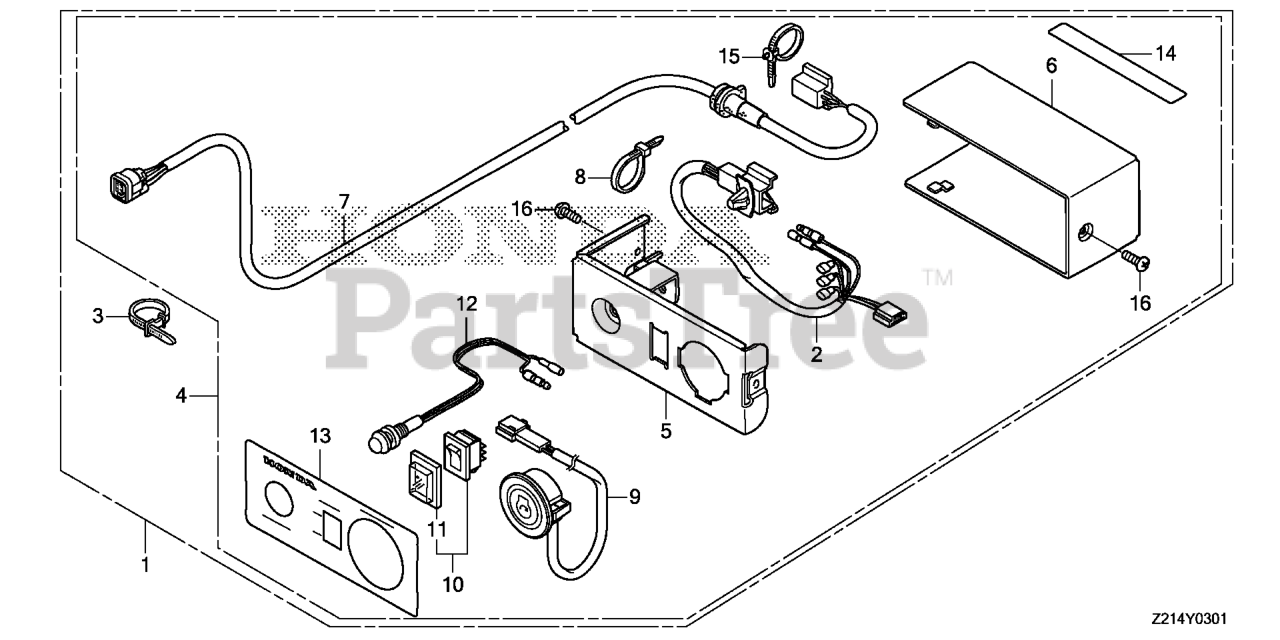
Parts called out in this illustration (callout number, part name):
1	CONTROL KIT, REMOTE (10M) *NH105* (MAT BLACK)
1	CONTROL KIT, REMOTE (20M) *NH105* (MAT BLACK)
1	CONTROL KIT, REMOTE (30M) *NH105* (MAT BLACK)
2	HARNESS ASSY., REMOTE CONTROL (AG)
3	BAND, WIRE Use up to Frame SN 1001879.
4	BOX ASSY., REMOTE CONTROL (10M) *NH105* (MAT BLACK)
4	BOX ASSY., REMOTE CONTROL (20M) *NH105* (MAT BLACK)
4	BOX ASSY., REMOTE CONTROL (30M) *NH105* (MAT BLACK)
5	PANEL, REMOTE CONTROL *NH105* (MAT BLACK)
6	COVER, REMOTE CONTROL *NH105* (MAT BLACK)
7	CABLE ASSY., REMOTE CONTROL (10M)
7	CABLE ASSY., REMOTE CONTROL (20M)
7	CABLE ASSY., REMOTE CONTROL (30M)
8	TIE, CABLE (C)
9	SWITCH ASSY., START
10	SWITCH ASSY., MAIN
11	CAP,SELECT SW
12	LED ASSY.
13	MARK, REMOTE CONTROL (NOT AVAILABLE)
14	MARK, SHUTOFF NOTE
15	BAND, HARNESS (98MM) (NATURAL)
16	SCREW, PAN (4X8)
